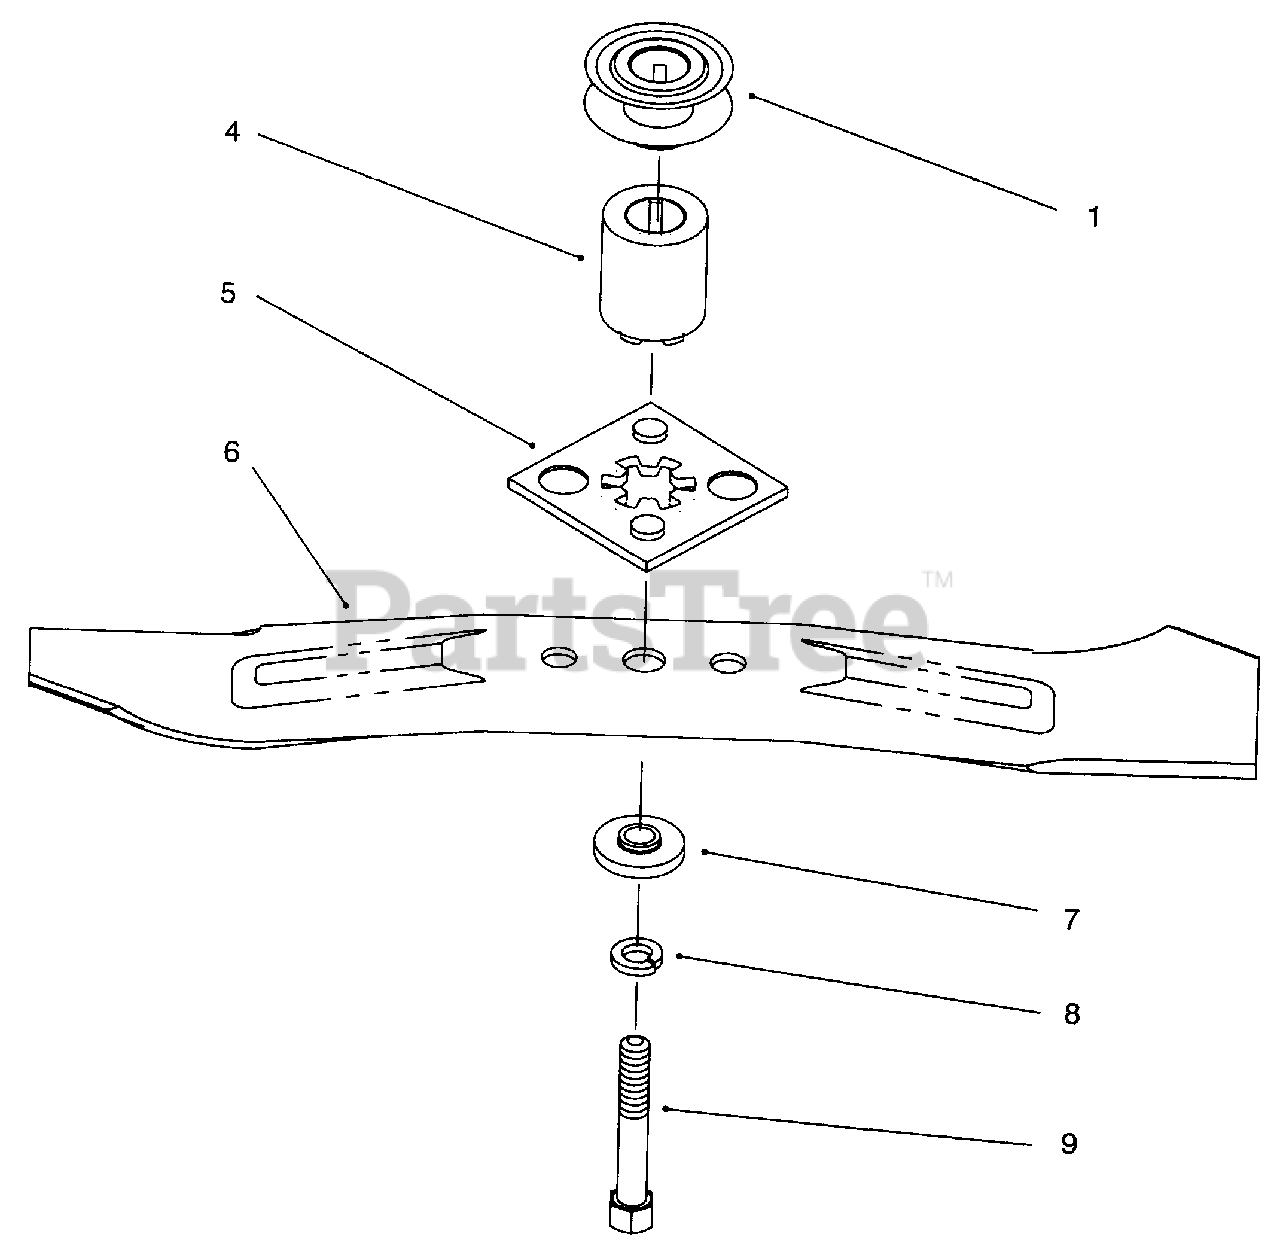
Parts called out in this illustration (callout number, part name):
1	Pulley-Driver
4	Hub-Blade Driver
5	Plate-Blade Driver
6	Blade-48 cm
7	Spacer-Blade
8	Washer-Lock
9	Bolt-Blade
